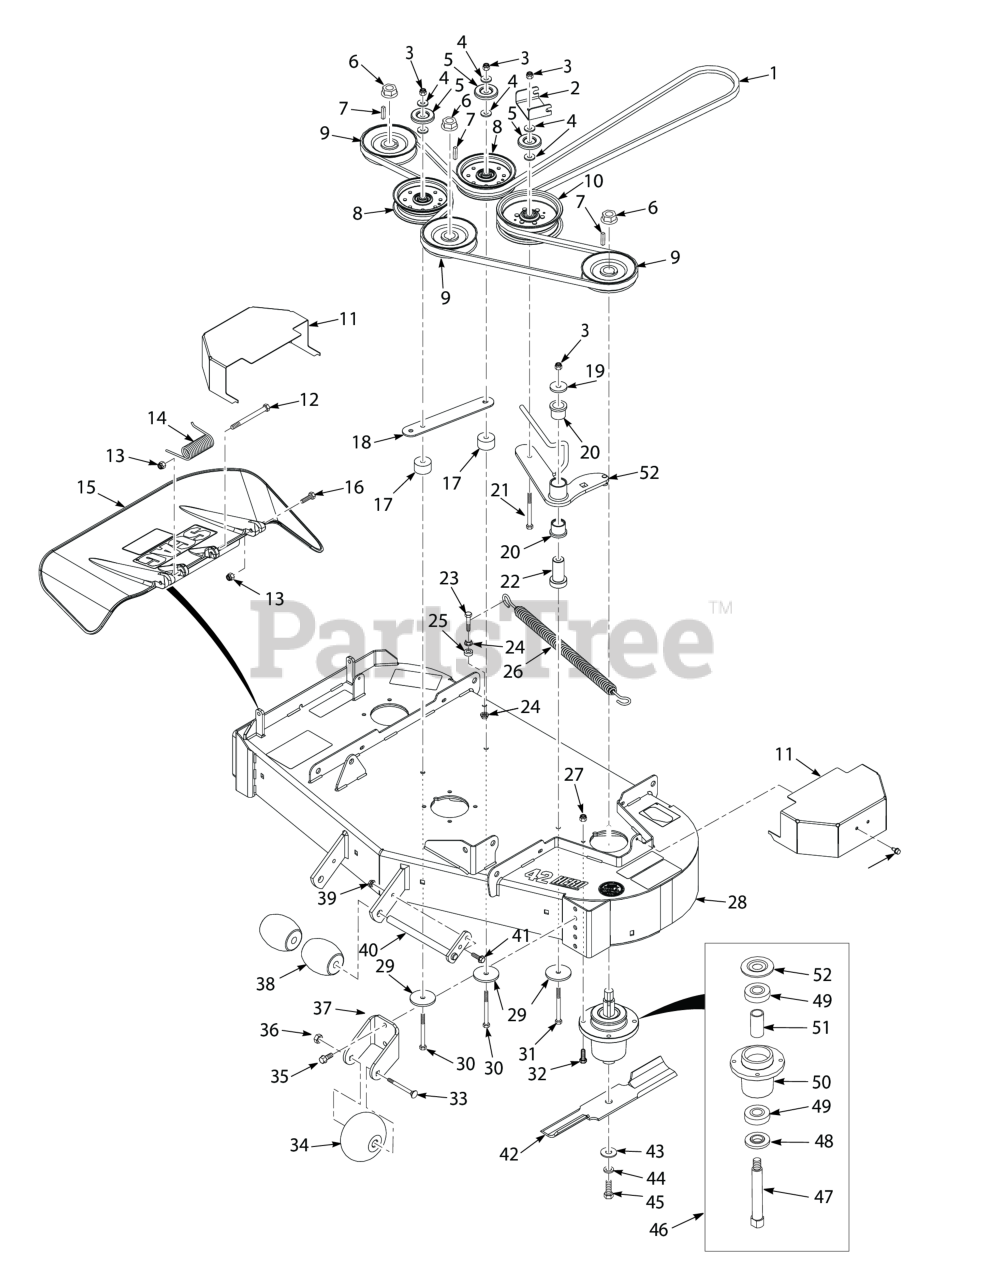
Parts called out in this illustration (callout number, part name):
1	Belt, Cutter Deck
2	Bracket, Belt Guide
3	HEX NUT, ELASTIC STOP LOCK, 3/8-16
4	Flatwasher, 3/8 (.391 x .938 x .105 HD) Grade 8
5	Quick Pin, 5/16" Dia.
6	Nut, 3/4-16 Spriral Lock
7	Key, 1/4 x 1/4 x 1.25" Pulley Mtg.
8	Pulley, Idler 4-1/2"
9	Pulley, 4.62"
10	Pulley, 5" Idler
11	Belt Cover
12	Bolt, 5/16-18 x 4-3/4" Hex Head
13	HEX NUT, ELASTIC STOP LOCK, 5/16-18
14	Spring, Discharge Chute
15	Discharge Chute
16	Bolt, Hex Head 5/16-18 x 1-1/2" - Front
17	Spacer, Idler Pulley
18	Brace, Pulley
19	Flat washer, 1/4-.266 x .875 x .125
20	Bearing, Plastic
21	Capscrew, Hex Head 3/8-16 x 2-1/2"
22	Pivot, Idler
23	Bolt, Hex Head 3/8-16 x 1-3/4" Grade 8 Black
24	NUT, 3/8-16 SERRATED FLANGE HEX HEAD
25	SPACER, IDLER
26	Spring, Cutter Deck Idler
27	Lock Nut, 5/16-18 Elastic Stop Grade 8
28	Cutter Deck w/Decals, SZL-42H
29	Flatwasher, 3/8-.406 x 2.25" x .1875
30	Bolt, Hex Head, 3/8-16 x 3-1/2"
31	Bolt, Hex Head 3/8-16 x 4.00
32	Bolt, Hex Head 5/16-18 x 1-1/2" Grade 8
33	Bolt, Hex Head 3/8-16 x 3-1/2"
34	Bolt, Carriage 3/8-16 x 4"
35	Capscrew, 3/8-16 x 1.0" Serrated Flange Hex Hd
36	Bolt, Hex Head 3/8-16 x 1" Ser. Flg.
37	Bracket, Anti-Scalp, (Black)
38	Wheel, Anti-Scalp
39	Nut, Flange Head Elastic Stop 5/16-18
40	Shaft Weldment, Guide Roller
41	Bolt, Heax Head 5/16-18 x 1" (48V / 52V)
42	Cutter Blade, 14-3/4"
43	Flatwasher, 5/8-.688 x 1-3/4 x .134 HD
44	Lockwasher, 5/8" Spring
45	Bolt, Hex Head 5/8-11 x 1-1/2"
46	Spindle Assembly
47	Shaft, Spindle
48	Protector, Bearing
49	Bearing
50	Spindle Housing
51	Spacer, Bearing
52	Idler Arm Assy. (incl. #20)
